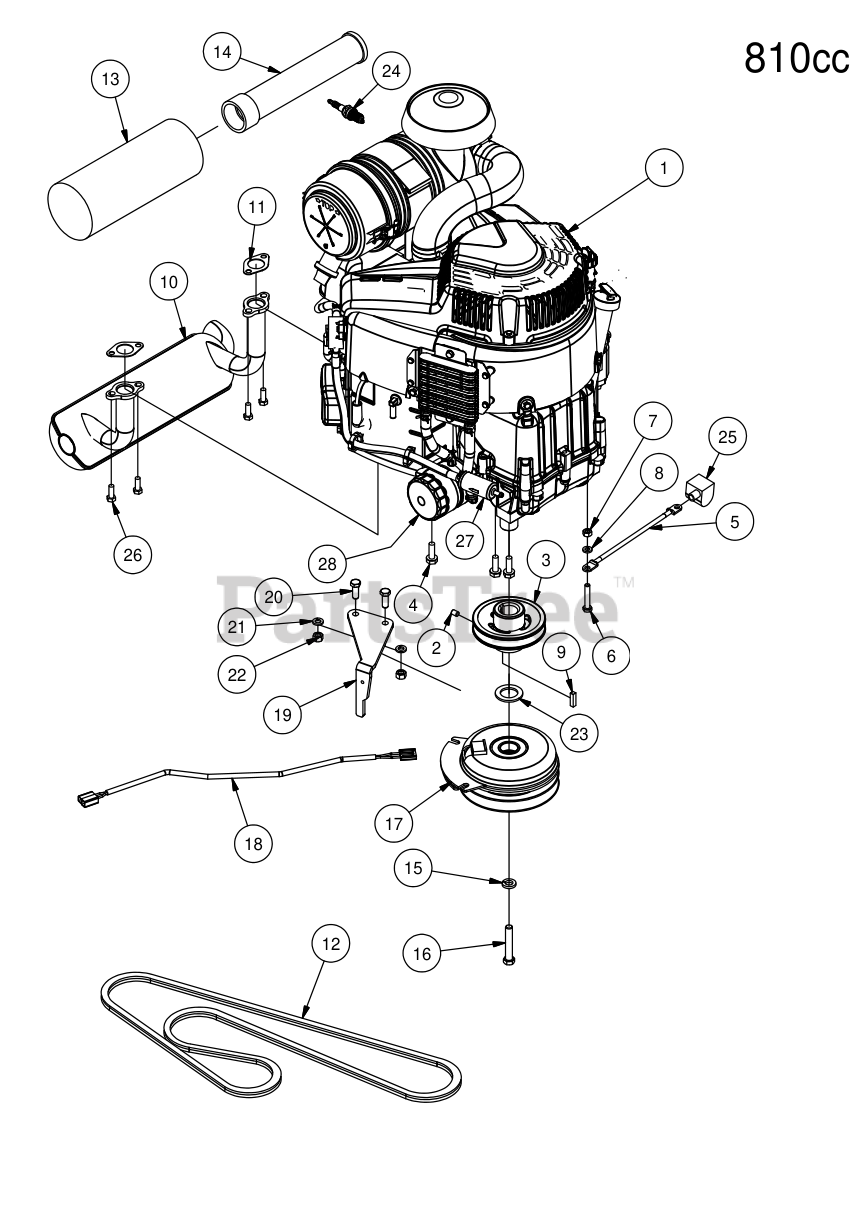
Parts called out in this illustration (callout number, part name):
1	810 Vanguard
2	3/8" Set Screw
3	4 3/4 Motor Pulley
4	3/8 x 1 1/8 bolt
5	Ground Cable
6	5/16" x 1 3/4" Hex Bolt
8	5/16" Lock Washer
9	1/4" x 1" Key
10	Briggs Exhaust
11	Exhaust Gasket
13	Canister Air Filter- Outer
14	Canister Air Filter- Inner
15	7/16" Lock Washer
16	7/16" x 2 1/2" Hex Bolt
17	Clutch Assembly
18	Clutch Pigtail
19	PTO Engager Holder
20	3/8" x 1" Hex Bolt
21	3/8" Lock Washer
22	3/8" Hex Nut
23	1 1/8" Flat Spacer
24	Spark Plug
25	Black Boot For Ground Cable
26	Torx Bolt-Exhaust
27	Universal Inline Fuel Filter
28	Briggs Oil Filter
